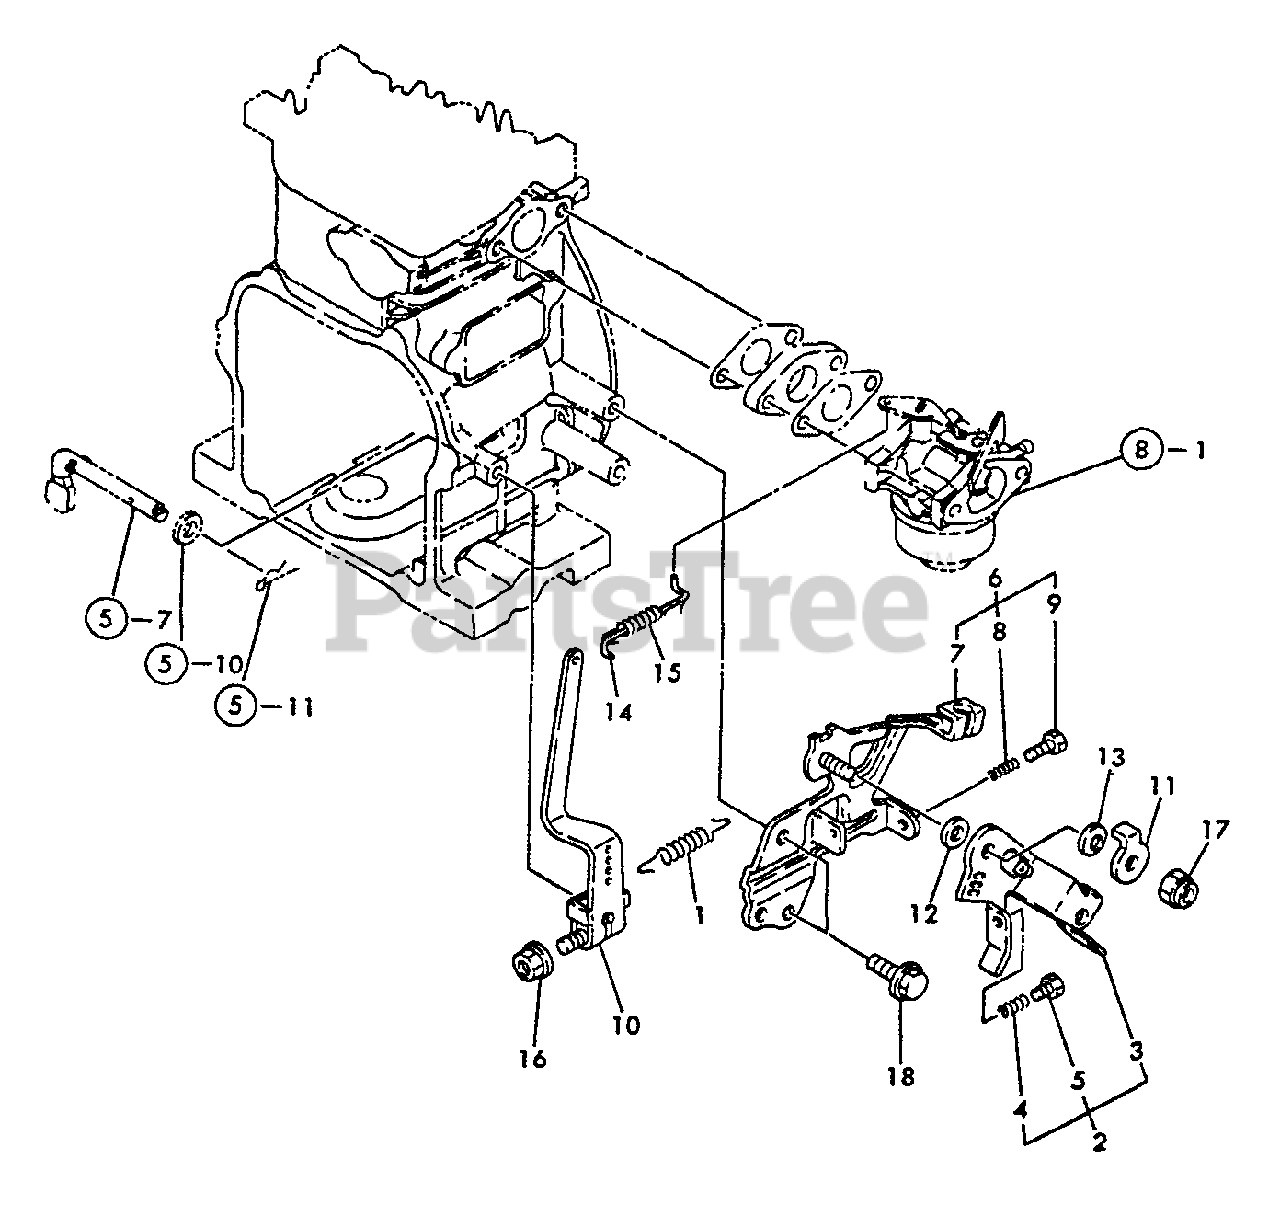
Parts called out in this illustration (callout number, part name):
1	SPRING, REGULATOR
2	REGULATOR HANDLE ASSY
3	HANDLE, REGULATOR
4	SPRING, IDLE
5	BOLT - 4X20
6	REGULATOR BASE ASSY
7	BASE, REGULATOR
8	SPRING, IDLE
9	BOLT - 4X25
10	LEVER, COVER
11	WASHER
12	WASHER - NYLON
13	SPRING, PLATE
14	LINK, THROTTLE
15	SPRING, THROTTLE
16	NUT - 6 -- FLANGE
17	NUT - 6
18	BOLT - 6X8 -- PLATED
